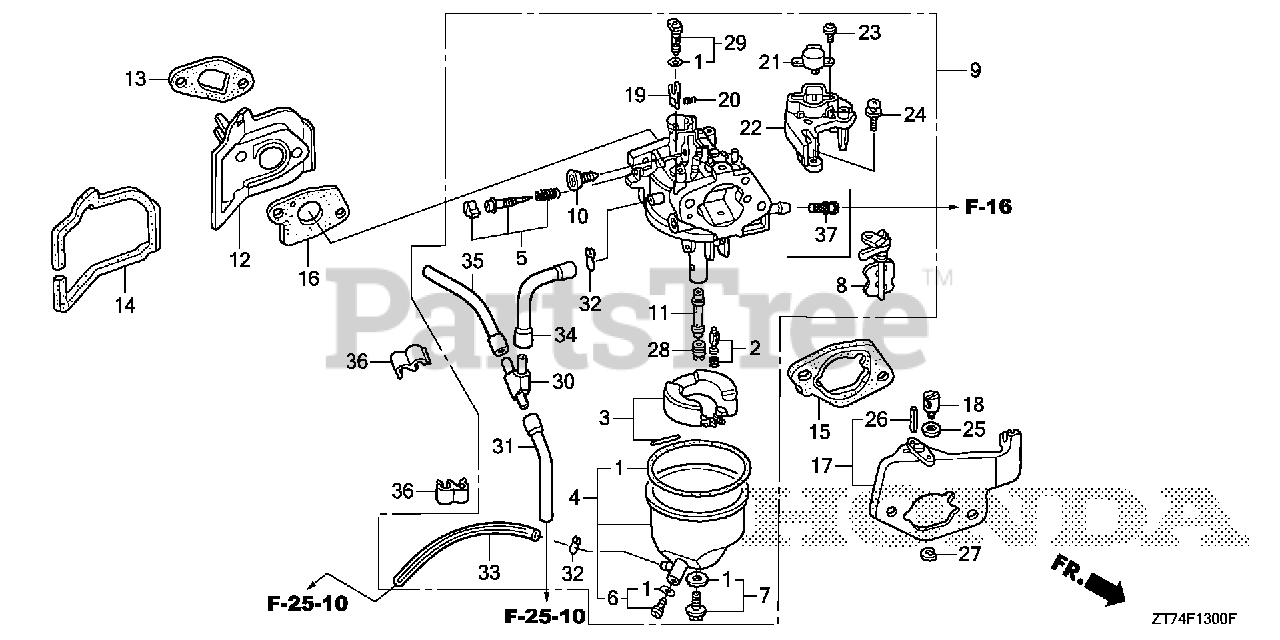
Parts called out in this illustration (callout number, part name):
1	GASKET SET
2	VALVE SET, FLOAT (CARBURETOR NO.) (SEAT NOT INCLUDED)
3	FLOAT SET
4	CHAMBER SET, FLOAT
6	SCREW SET, DRAIN (CARBURETOR NO.)
7	SCREW SET (CARBURETOR NO.)
8	CHOKE SET (CARBURETOR NO.)
9	CARBURETOR ASSY. (BEA0M A) (NOT AVAILABLE)
10	SCREW, THROTTLE STOP
11	NOZZLE, MAIN (NOT AVAILABLE)
12	INSULATOR, CARBURETOR
13	GASKET, INSULATOR
14	SEAL, CARBURETOR INSULATOR
15	GASKET, AIR CLEANER
16	GASKET, CARBURETOR
17	STAY, CHOKE
18	HOLDER, CABLE
19	LEVER, LINK (CARBURETOR NO.)
20	SPRING, COMPRESSION COIL (CARBURETOR NO.)
21	MOTOR, THROTTLE CONTROL
22	BRACKET, THROTTLE MOTOR
23	SCREW-WASHER (3X8)
24	SCREW-WASHER (4X10)
25	WASHER, PLAIN (6MM)
26	PIN, SPRING (2X18)
27	E-RING (5MM)
28	JET, MAIN (#72) (CARBURETOR NO.)
28	JET, MAIN (#75) (CARBURETOR NO.)
28	JET, MAIN (#70)
29	JET SET, PILOT (#45) (CARBURETOR NO.)
30	JOINT, AIR VENT TUBE (CARBURETOR NO.)
31	TUBE, AIR VENT (CARBURETOR NO.)
32	CLIP, TUBE (C6.5) (CARBURETOR NO.)
33	BULK HOSE, VINYL (3.5X6.5X8000) (9500(95003-05001-60M) (CARBURETOR NO.)
34	BULK HOSE, VINYL (4X7X8000) (95003-07(95003-07001-60M) (CARBURETOR NO.)
35	BULK HOSE, VINYL (4X7X8000) (95003-07(95003-07001-60M) (CARBURETOR NO.)
36	CLAMP, TUBE (7.5X2)
37	SCREEN, FUEL STRAINER
